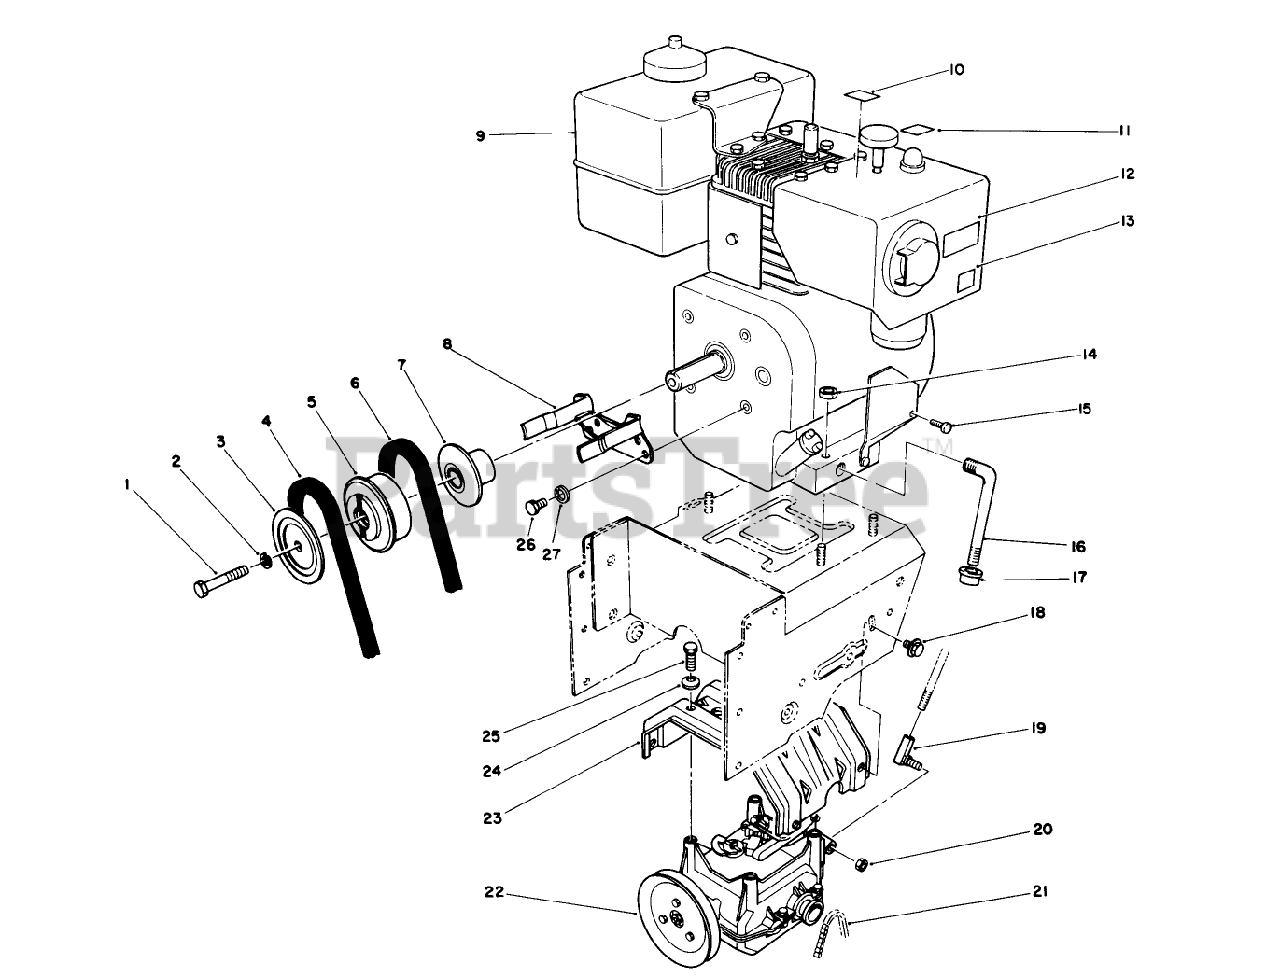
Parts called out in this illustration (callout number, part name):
1	SCREW-HH
2	WASHER-LOCK
3	SHEAVE-HALF, IMPELLER
4	V-BELT
5	PULLEY-ENGINE, CENTER
6	V-BELT, TRACTION
10	DECAL - THROTTLE, INT'L
12	DECAL-WARNING, HOT SURFACE
13	DECAL - CHOKE
14	NUT-HF
17	CAP-PIPE
18	SCREW-HHF
20	NUT-LOCK, NI
22	TRACTION GEARCASE ASM
24	WASHER-SPRING
26	SCREW-HH
27	WASHER-LOCK
